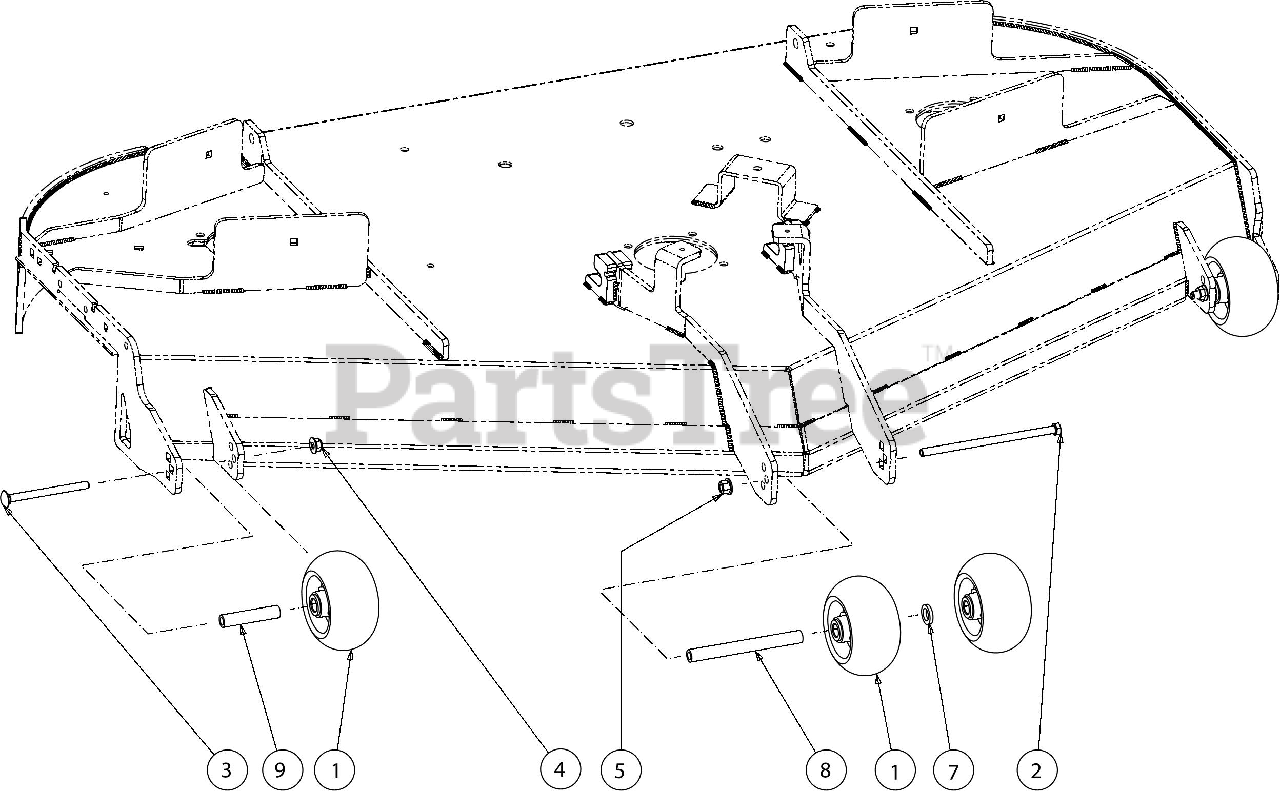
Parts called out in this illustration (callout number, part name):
1	WHEEL ASSEMBLY 5"
1	GREASE FITTING
1	FLANGE BEARING
2	SCREW 3/8-16 X 7.25 GR5
3	CARRIAGE BOLT 3/8-16 X 4.25 GR5
5	NUT-CTRLCK FLG HEX
6	FLAT WASHER
7	FLAT WASHER .632X1.00X.16
8	WHEEL SPACER
9	WHEEL SPACER .38ID X 3.04LG
